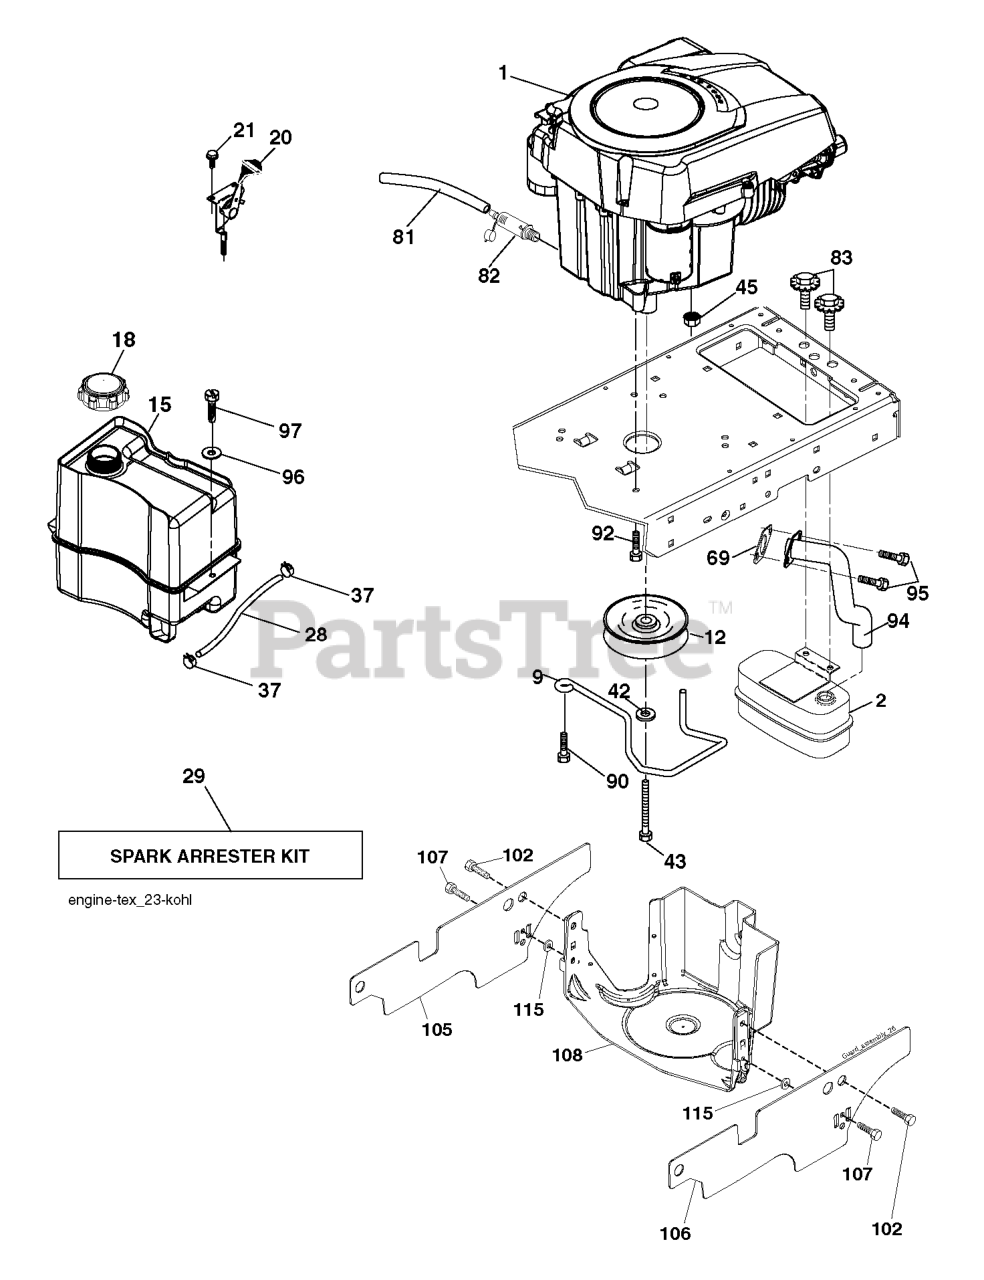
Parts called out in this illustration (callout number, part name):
2	MUFFLER.SINGLE.CYL.KOHL/B&S
9	KEEPER.BELT.ENGINE.4.2
12	PULLY ENGINE
15	RP TANK FUEL FRT 1.5 GAL
18	FUEL CAP
20	CONTROL.TH/CK.C.
21	SCREW.#10 X 0.750.BOS
28	LINE.FUEL.20
29	KIT.SPARK ARRESTOR 794945 B&S
37	HOSE CLAMP
42	LOCKWASHER
43	BOLT HEX 7/16-20X4-1/4"
45	NUT
69	GASKET.EXHAUST.KOHLER
81	TUBE, DRAIN OIL ASM.
82	PLUG DRAIN OIL EASY
83	BOLT.5/16-18UNCX3/4 W/SEMS.BLK
90	SCREW 3/8-16X1
92	SCREW 3/8-16X1
94	RP.TUBE.EXHAUST.KOHL.COURAGE
95	SCREW.SOCKET HD.5/16-1
97	SCREW HEXWSHR 1/4-20X3/4
102	SCREW
105	SHIELD.SIDE.LH.3842"TEX FRENCH
106	SHIELD.SIDE.RH.3842"TEX FRENCH
107	SCREW.1/4-20X5/8
108	ENGINE COVER
115	PALNUT 1/4
